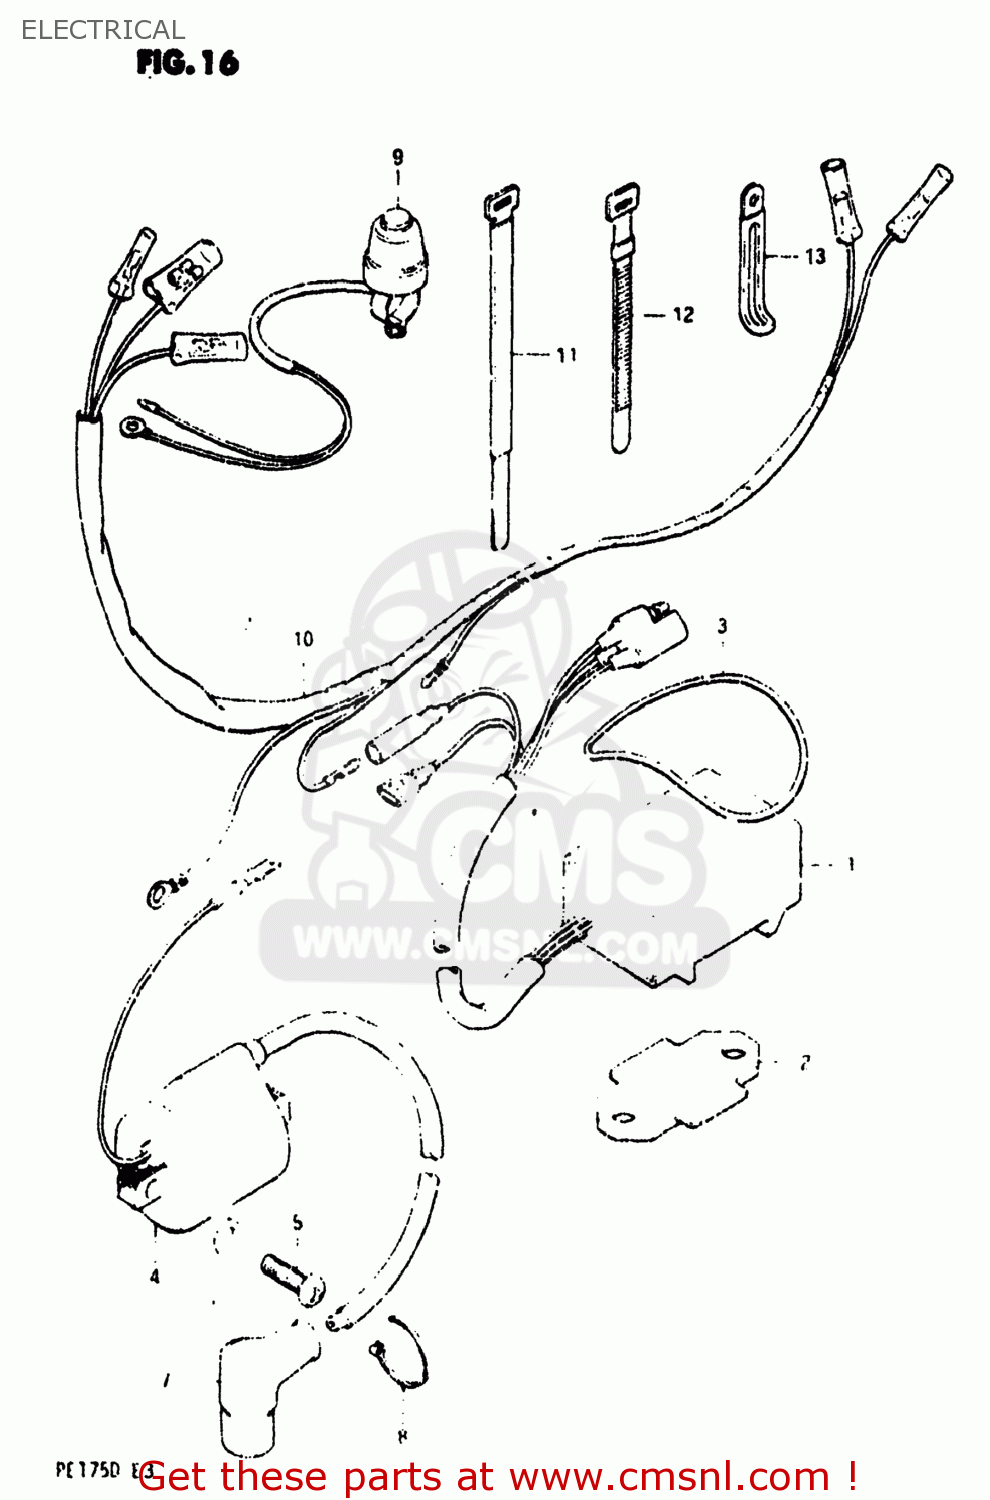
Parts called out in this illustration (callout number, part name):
1	CDI UNIT
2	PROTECTOR,CDI UNIT
3	O-RING
4	COIL ASSEMBLY,IGNITION
5	SCREW
6	LOCK WASHER
7	CAP,SPARK PLUG
8	CLAMP
9	SWITCH ASSEMBLY
10	HARNESS,WIRING
11	CLAMP
12	CLAMP(L:120)
13	CLAMP
